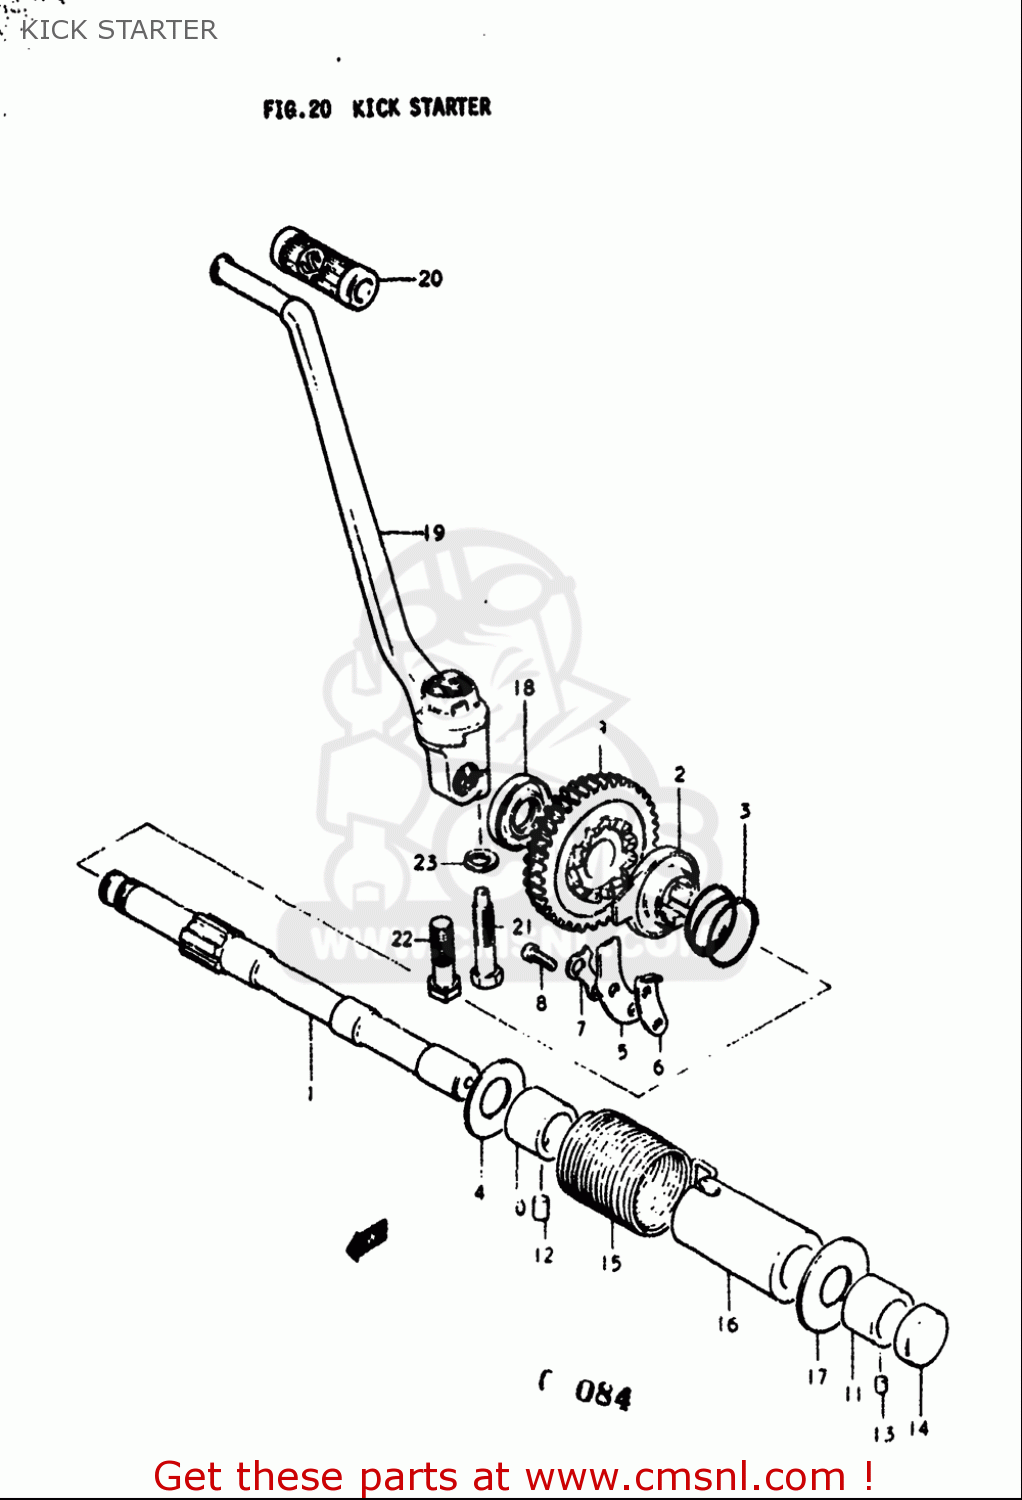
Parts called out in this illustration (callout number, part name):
2	STARTER,KICK
3	SPRING
4	WASHER
5	GUIDE,KICK STARTER
7	WASHER
8	BOLT(6X14)
12	PIN
13	PIN
14	PLUG
15	SPRING
18	SEAL,OIL(16X30X8)
20	RUBBER,KICK STARTER PEDAL
21	BOLT
22	BOLT
23	WASHER,LOCK
